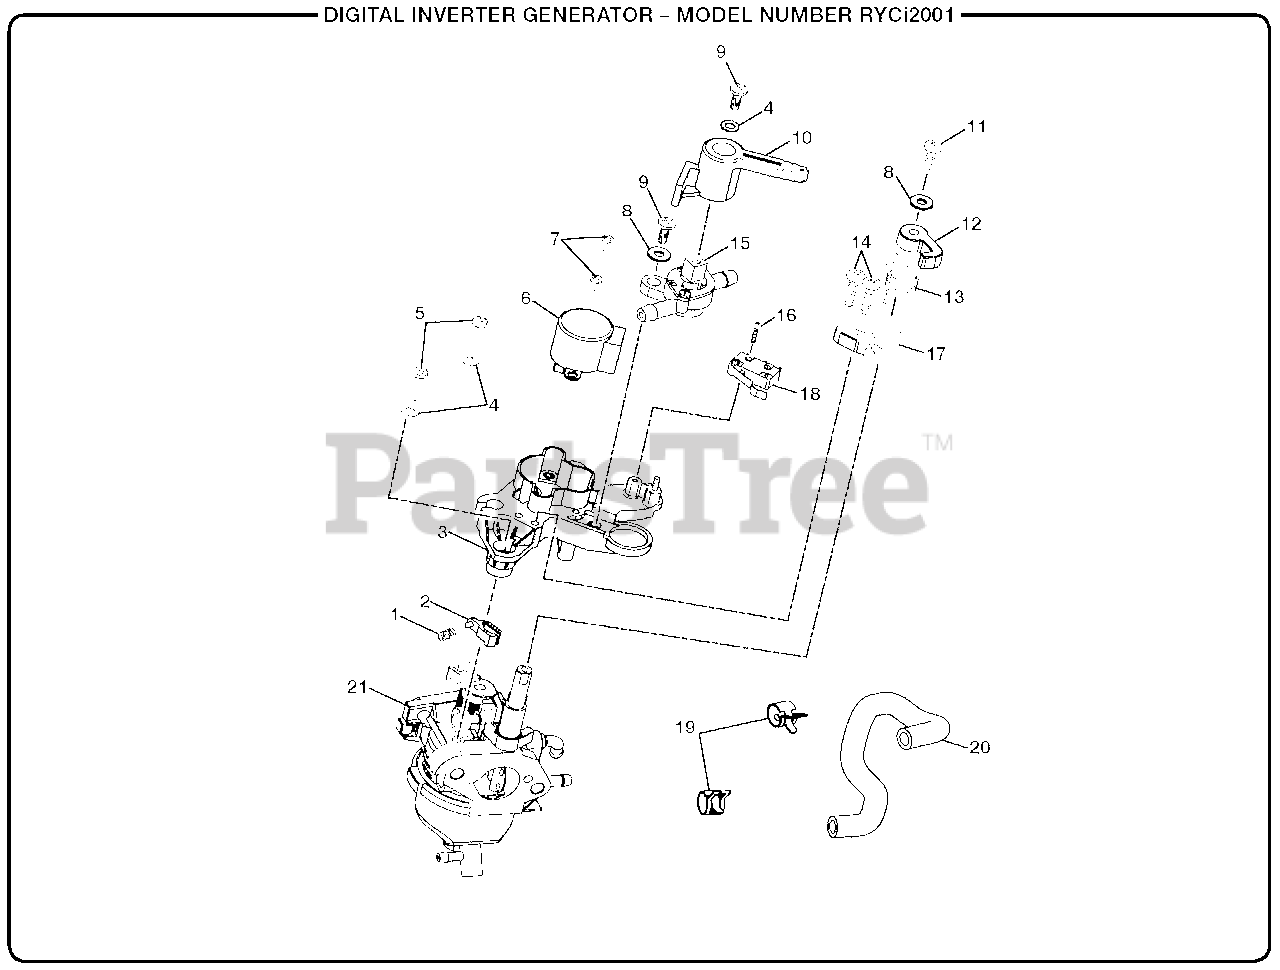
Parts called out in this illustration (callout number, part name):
1	Governor Damping Spring
2	Governor Joint
3	Governor Motor Bottom Housing
4	Washer (M4)
5	Screw (M4 x 14 mm, Phillips Pan Hd)
7	Screw (M3 x 5 mm, Phillips Pan Hd)
8	Washer (OD10 x ID42 x 1t)
9	Screw (M4 x 10 mm, Phillips Pan Hd)
10	Control Lever
11	Screw (ST42 x 12 mm, Phillips Pan Hd)
12	Choke Lever Upper
14	Screw (ST42 x 16 mm, Phillips Pan Hd)
15	Fuel Valve
16	Screw (M3 x 08 mm, Phillips Pan Hd)
17	Support Bracket
18	Engine Shut-Off Switch
19	Clamp (95 mm)
20	Fuel Hose (Fuel Valve To Carb)
21	Carburetor
